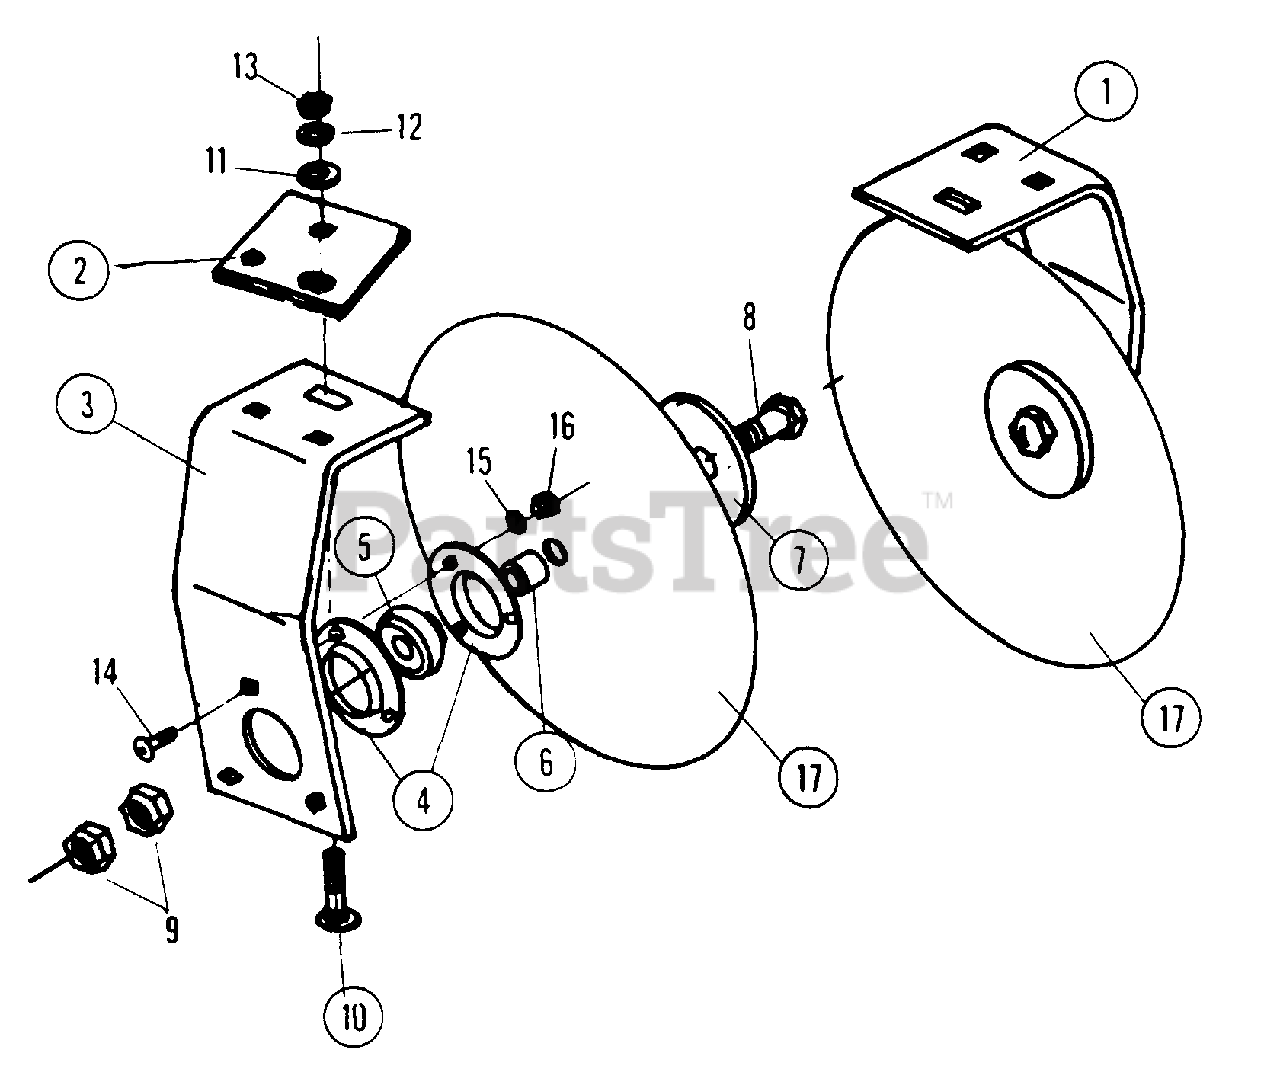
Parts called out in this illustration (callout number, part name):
1	PLATE, RIGHT HAND MOUNTING
2	CLAMP-PLATE
3	PLATE, LEFT HAND MOUNTING
4	FLANGETTE
5	BEARING, 1-1/4
6	BUSHING
7	WASHER, REINFORCING
8	BOLT, 1" x 3" HEX HEAD
9	NUT, 1" HEX JAM
10	BOLT, 1/2 x 2-3/4 CARRIAGE
11	WASHER, 1/2 PLAIN
12	LOCKWASHER, 1/2"
13	NUT, 1/2" HEX
14	BOLT, 3/8 x 1" CARRIAGE
15	LOCKWASHER, 3/8
16	NUT, 3/8 HEX
17	DISC-BLADE
